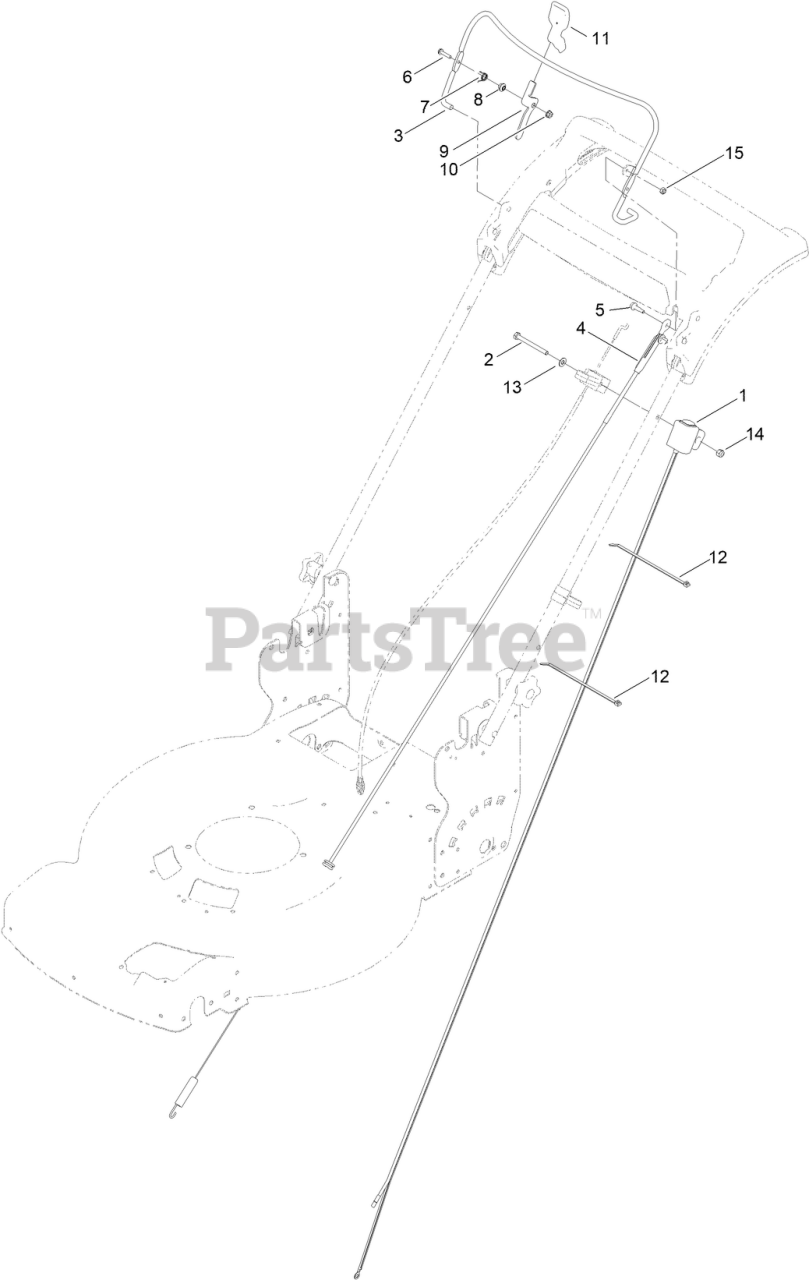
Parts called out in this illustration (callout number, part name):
1	SWITCH HOUSING ASM
2	SCREW-HH
3	BAIL-BRAKE [BLACK]
4	CABLE-BRAKE
5	SCREW-SHOULDER
6	SCREW-HWH
7	SPRING-TORSION
8	SPACER
10	NUT-HEX FLANGE
12	TIE-CABLE
13	WASHER-FLAT
14	NUT-LOCK, NI
15	NUT-HEX
